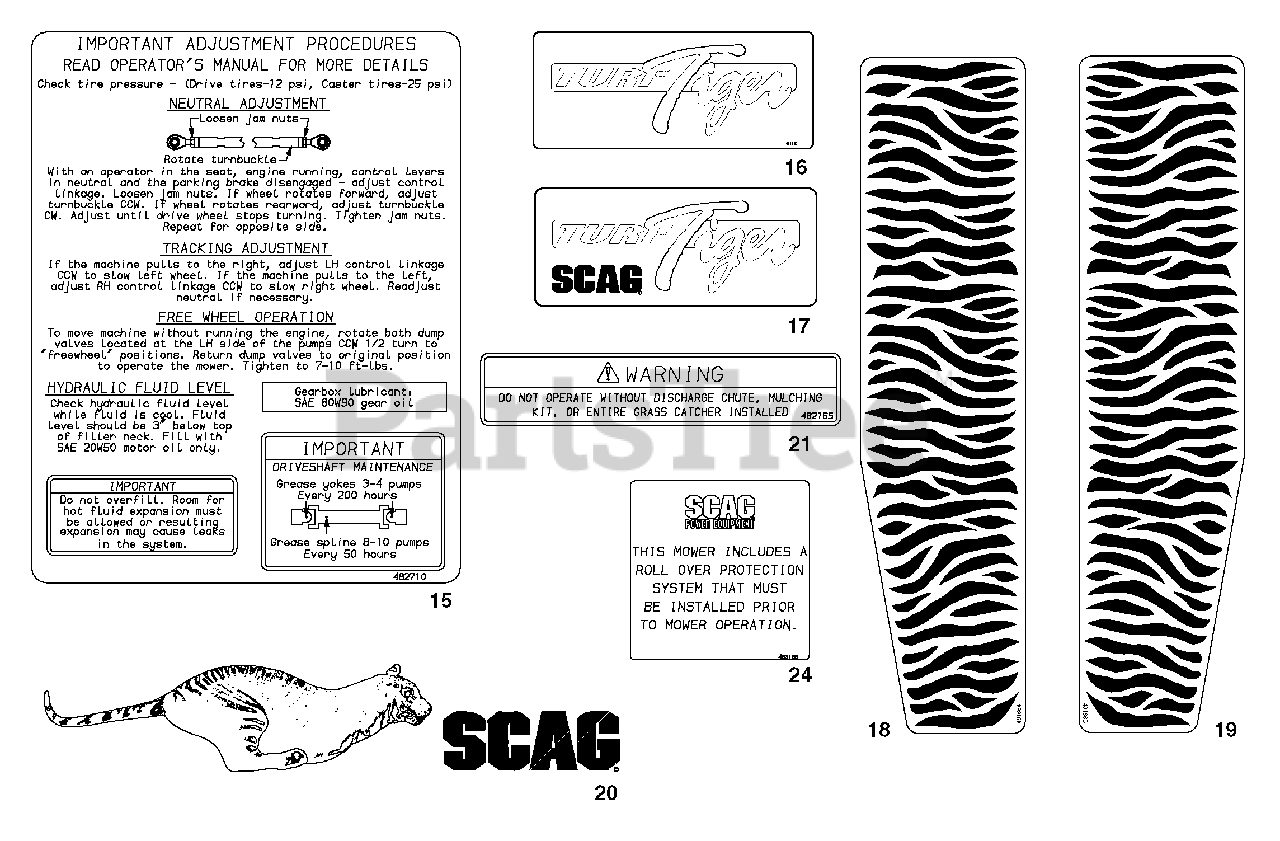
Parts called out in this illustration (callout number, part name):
15	Decal, Seat Support
16	Decal, Turf Tiger
17	Decal, Turf Tiger
18	Decal, Stripes-RH
19	Decal, Stripes-LH
20	Decal, Tiger
21	Decal, Warning
24	Decal, ROPS
